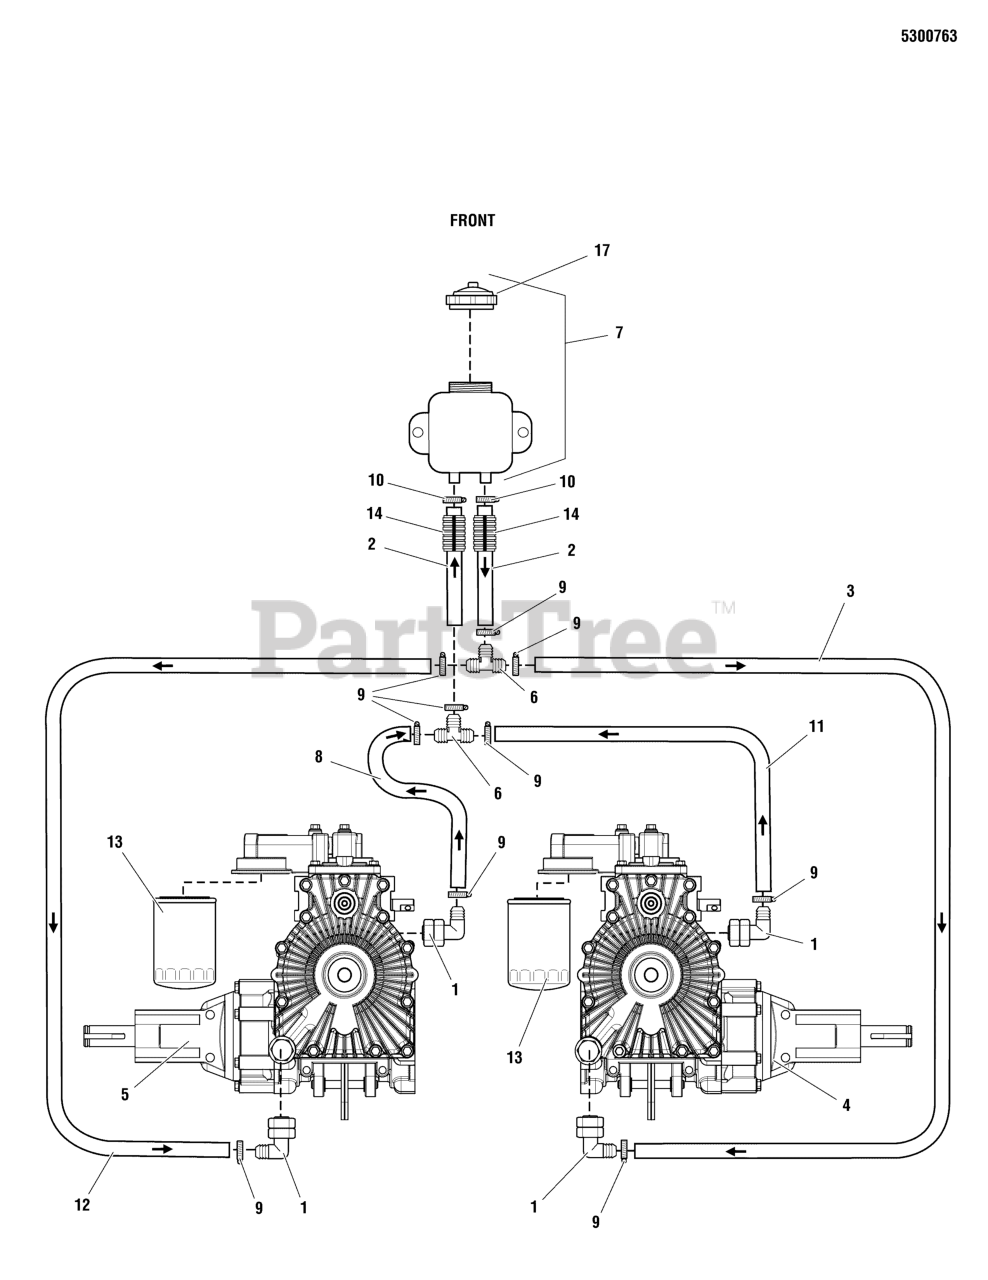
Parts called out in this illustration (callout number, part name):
1	FITTING, 90 DEG.
2	HOSE, 1/2" X 29 PUSH-ON
3	HOSE, 3/8" X 30.5 PUSH-LOCK
4	TRANSAXLE, 771-101, RIGHT SIDE
5	TRANSAXLE, 771-102, LEFT SIDE
6	FITTING, HYD, HOSE BARB TEE
7	RESERVOIR, TANK W/ CAP
8	HOSE, 3/8" X 10.5 PUSH-LOCK
9	CLAMP, HOSE
10	CLAMP, #10 HOSE, STAINLESS
11	HOSE, 3/8" X 16.5 PUSH-LOCK
12	HOSE, 3/8" X 19.5 PUSH-LOCK
13	FILTER, TRANSMISSION OIL
14	WIRE LOOM, 5/8 ID
17	RESERVIOR CAP
